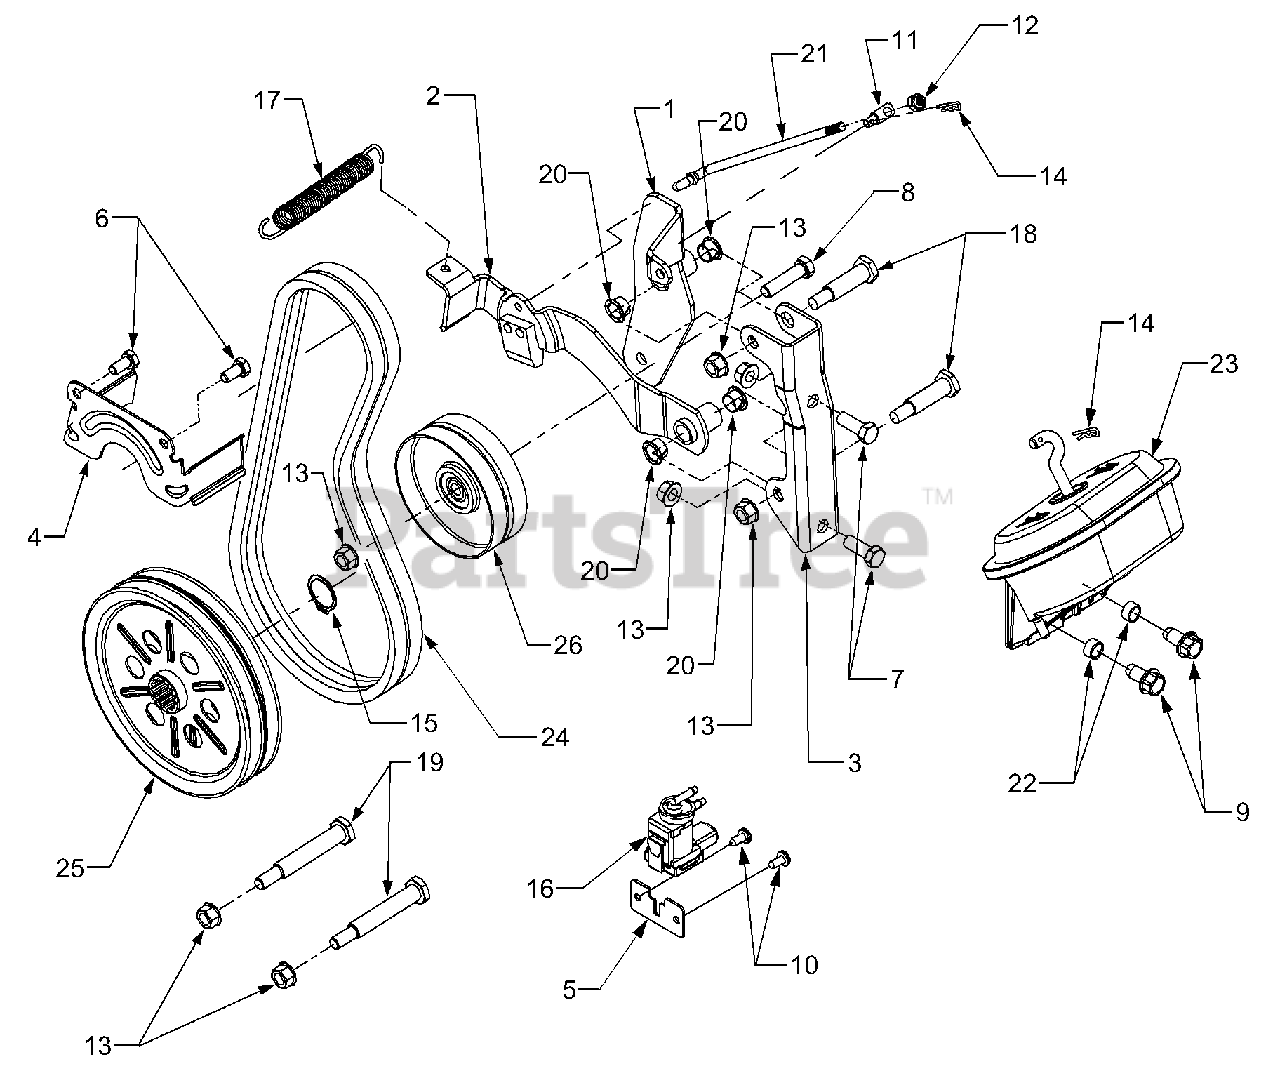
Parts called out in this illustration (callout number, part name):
1	Bracket, Idler
2	Bracket Assembly, Brake
3	Bracket, PTO Mounting
5	Bracket, Solenoid Mounting
6	Screw, Hex Cap 5/16-24 x .625 GR5
7	Screw, Hex Cap 3/8-16 x 1.0 GR5
8	Screw, Hex Cap 3/8-16 x 1.5 GR5
9	Screw, Hex Wash. Hd. Tapp 3/8-16 x .75
10	Screw, Phil. Hd. Tapp #12-14 x .5
11	Ferrule, Brake Adjustment
12	Nut, Hex Insert Lock, 1/4-20
13	Nut, Flange Lock, 3/8-16
14	Pin, Internal Cotter
15	Snap Ring, 1.0 Dia Shaft
16	Solenoid, Kit Vacuum Actuator
17	Spring, Extension, .530 x 4.74
18	Shoulder Screw, .498 x 1.45
19	Shoulder Screw
20	Bearing, Nylon Flange
21	Rod, PTO Brake
22	Spacer, .380 x .5 x .265
23	Vacuum Actuator
24	V-Belt, A-Section x 37.63 (Set of two belts)
25	Pulley, PTO Drive. 6.75-Double
26	Pulley, Flat Idler, 4.0
